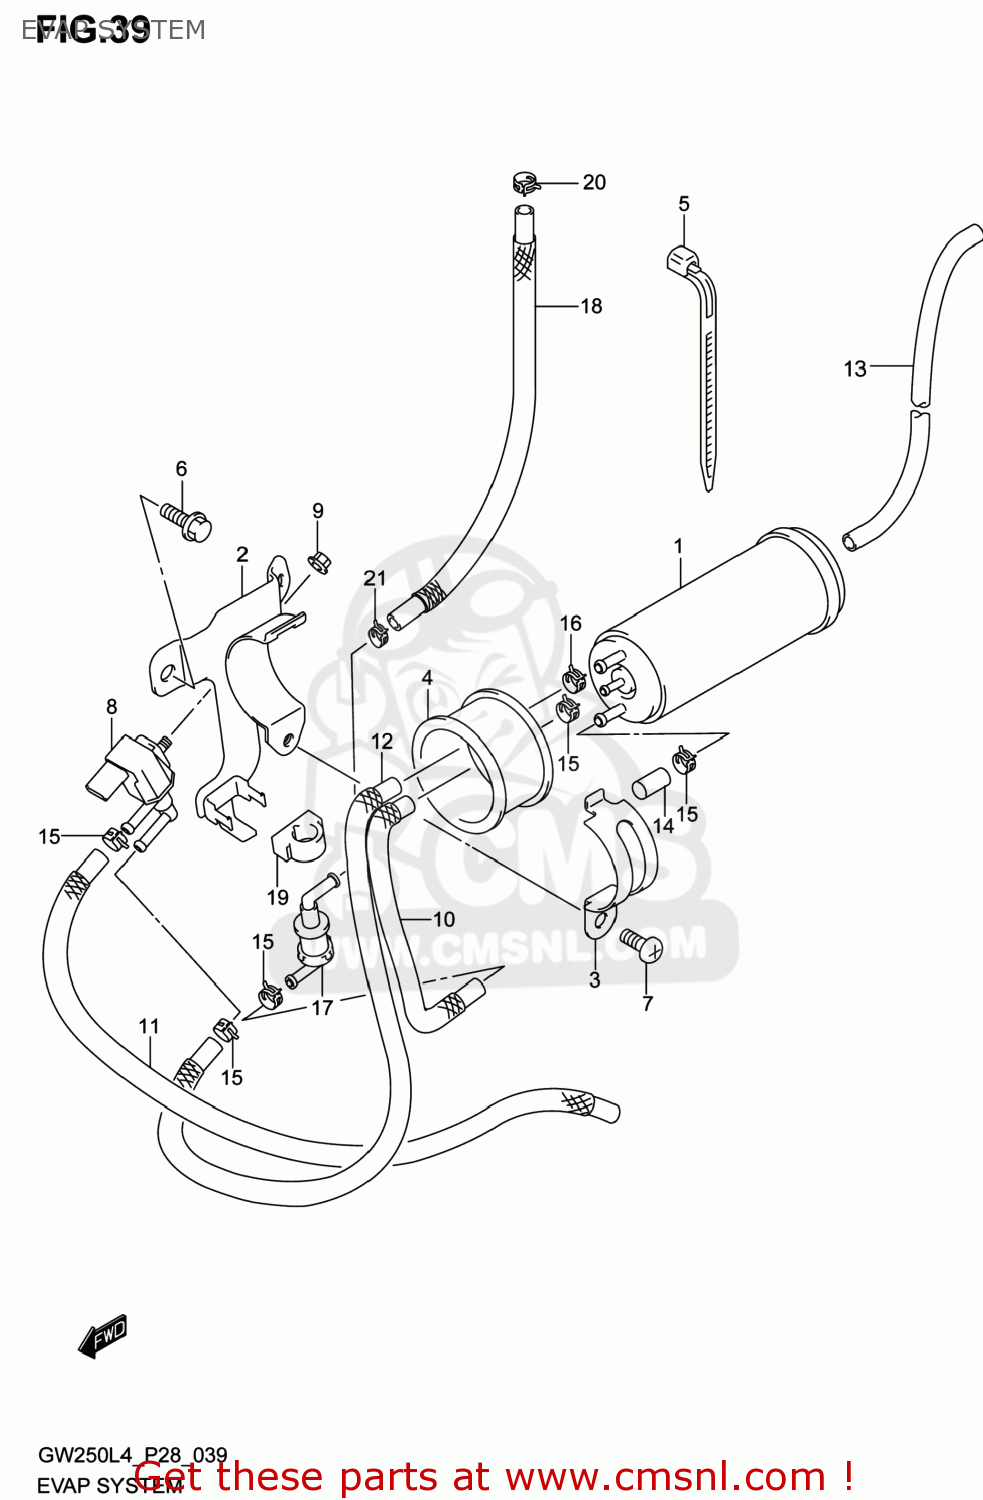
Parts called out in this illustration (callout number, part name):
1	CANISTER ASSY,CHARCOAL
2	BRACKET,CANISTER
3	HOLDER,CANISTER
4	CUSHION,CANISTER
5	CLAMP(L:165)
6	BOLT
7	SCREW
8	VALVE,CANISTER PURGE
9	NUT
10	HOSE,CANISTER INLET
11	HOSE,PURGE VALVE
12	HOSE,CANISTER PURGE
13	HOSE,CANISTER AIR
14	CAP
15	CLIP
16	CLIP
17	VALVE,FUEL TANK BREATHER
18	HOSE,TANK & BREATHER VALVE
19	CUSHION,FUEL TANK BRTHR VALVE
20	CLIP
21	CLIP
